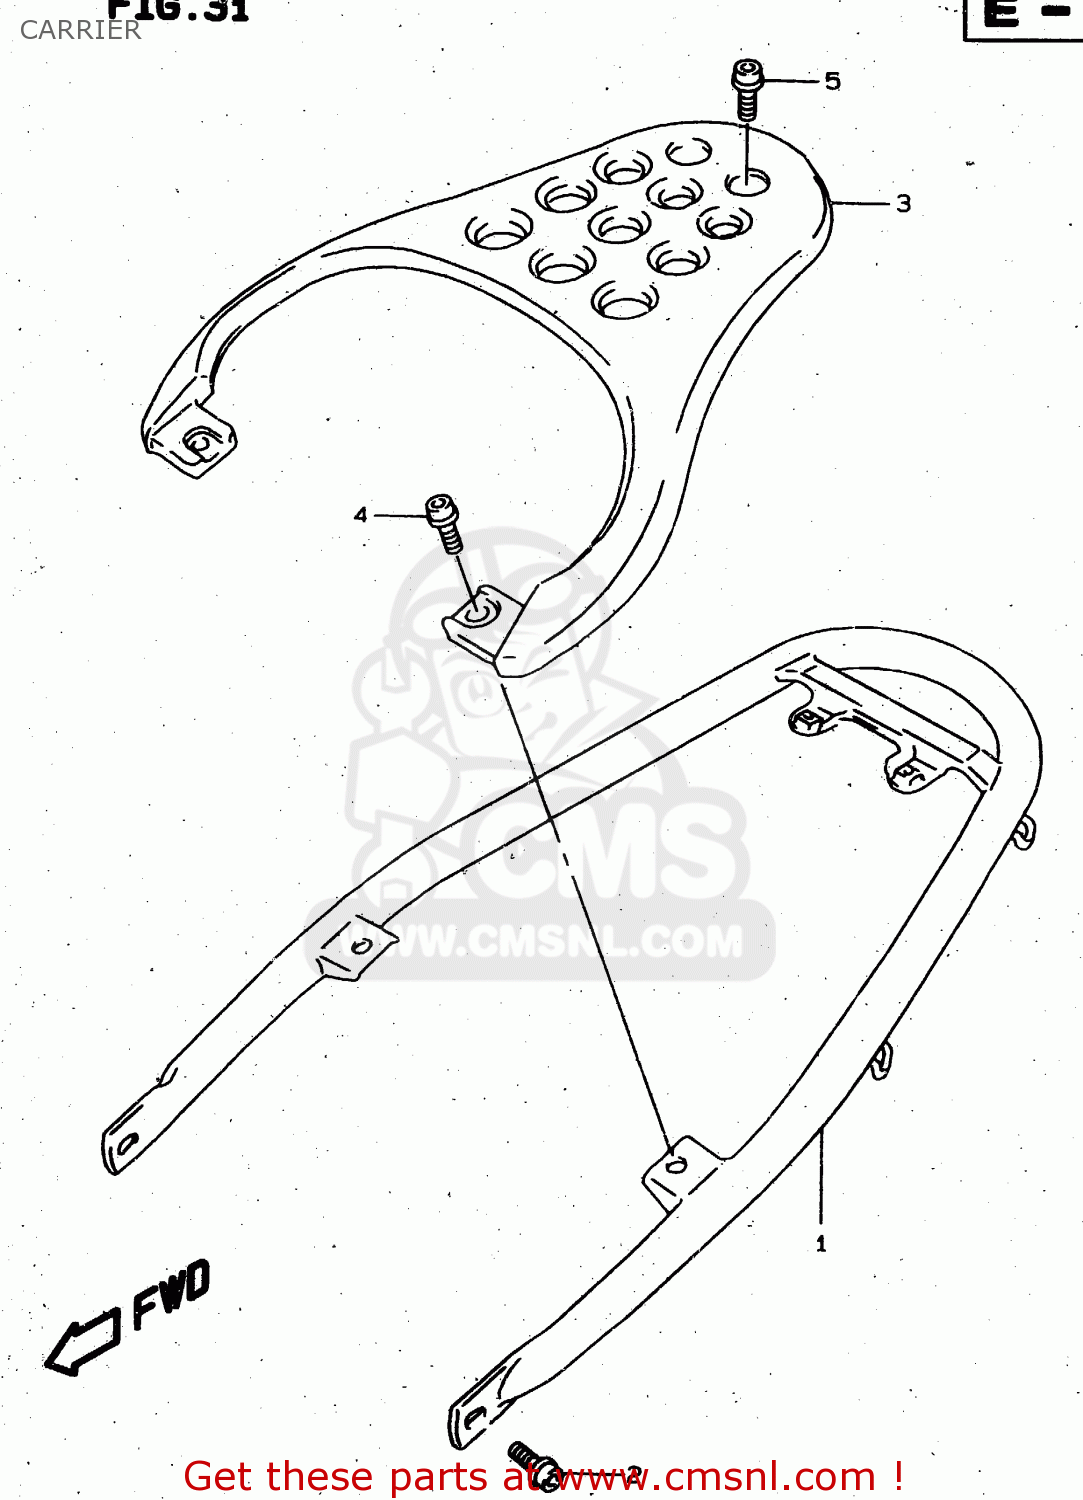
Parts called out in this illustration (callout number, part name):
1	FRAME,RR(ORANGE)
2	BOLT
3	CARRIER,SPORT
4	BOLT
5	BOLT
